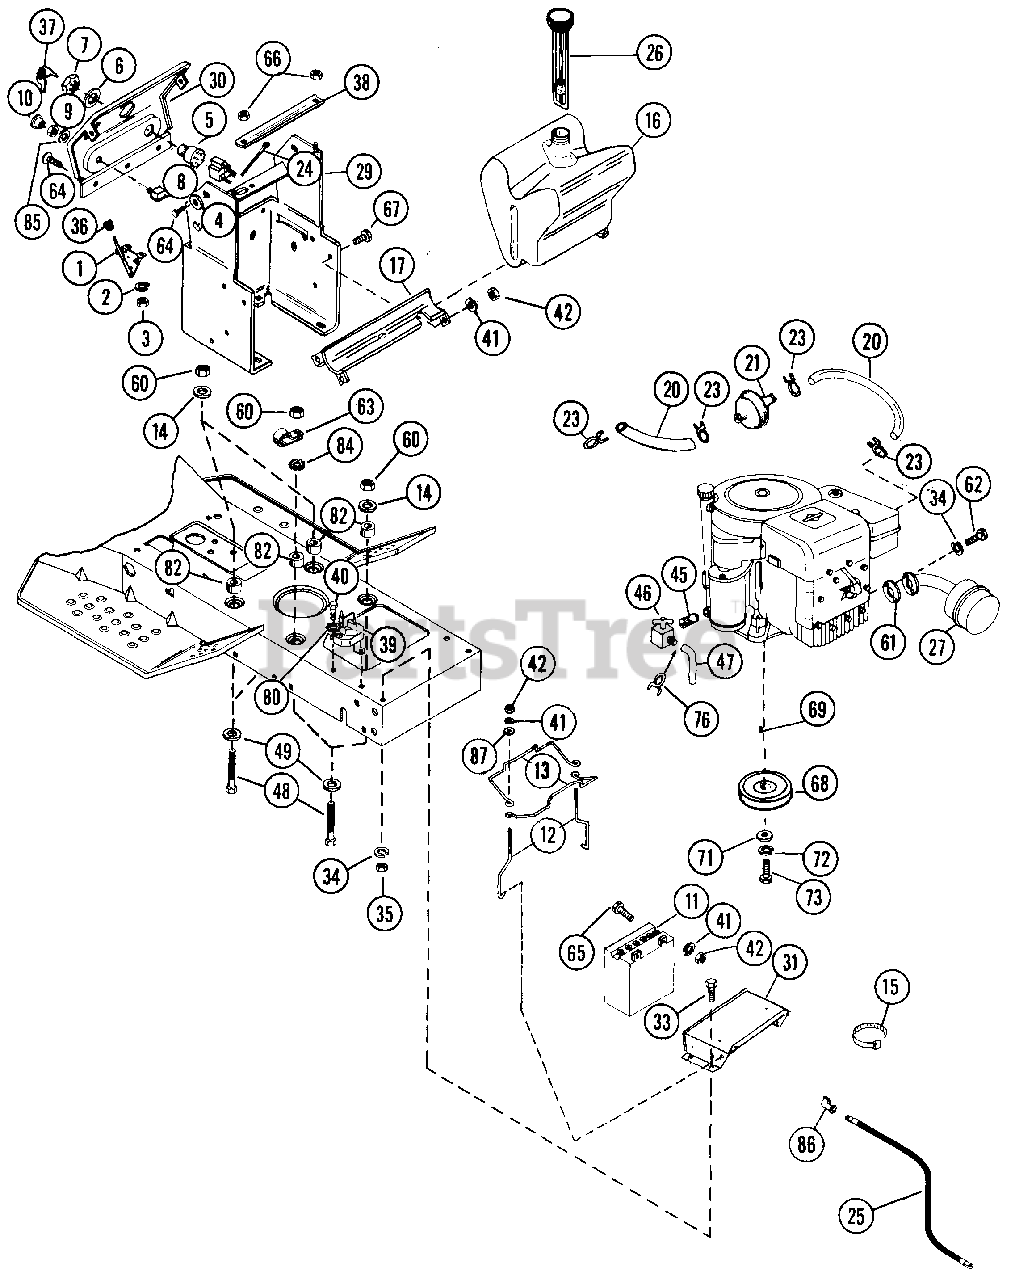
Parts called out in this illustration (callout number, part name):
1	THROTTLE CONTROL
2	WASHER, LOCK NO. 10 SP.
3	NUT
4	WASHER, FLAT .250X.500X.049
5	IGNITION SWITCH
6	WASHER, LOCK INT. TOOTH
7	NUT, JAM 9/16-24
8	LIGHT SWITCH
9	NUT, HEX 1/2-20
10	KNOB
11	BATTERY, 12 VOLT SMALL
12	TIE DOWN
13	HOLD DOWN
14	WASHER, FLAT .312X.734X.065
15	TIE, CABLE
16	FUEL TANK
17	LOWER TANK SUPPORT
20	HOSE
21	FUEL FILTER
23	HOSE CLAMP
24	TIE DOWN
25	CABLE, BATTERY TO ENGINE BASE
26	FUEL GAUGE
27	EXHAUST MUFFLER
29	DASH BASE
30	DASH
31	BATTERY STAND
33	BOLT, HEX 5/16-18X.625
34	WASHER, LOCK 3/8 SP HEAVY
35	NUT, HEX 5/16-18
36	KNOB
37	KEY, IGNITION SWITCH
38	CLAMP, STRAP
39	SOLENOID
40	SCREW, TAPTITE 1/4-20X.375
41	WASHER, LOCK 1/4 REG.
42	NUT, HEX 1/4-20
45	BUSHING
46	DRAIN LOCK
47	TUBE
48	BOLT, HEX 5/16-18X2.00
49	WASHER, 5/16X1-5/8X.135
60	NUT, LOCK 5/16-18
61	GASKET
62	BOLT, HEX 5/16-18X.75
63	J-CLAMP
64	SCREW, TAPPING 10-16X3/8
65	BOLT, HEX 1/4-20X.875
66	NUT, LOCK 1/4-20
67	BOLT, HEX 1/4-20X.50
68	SHEAVE, ENGINE
69	KEY, STRAIGHT 1/4X2X1/4
71	WASHER, FLAT .500X1.250X.083
72	WASHER, LOCK SP HEAVY
73	BOLT, HEX 7/16-20X1
76	HOSE CLAMP
79	CLIP
80	WASHER, LOCK 1/4 EXT.
82	ENGINE SPACER
84	WASHER, LOCK 5/16 EXT TH TYA
85	WASHER
86	BOOT, BATTERY CABLE
87	WASHER, FLAT .281X.625X.065
